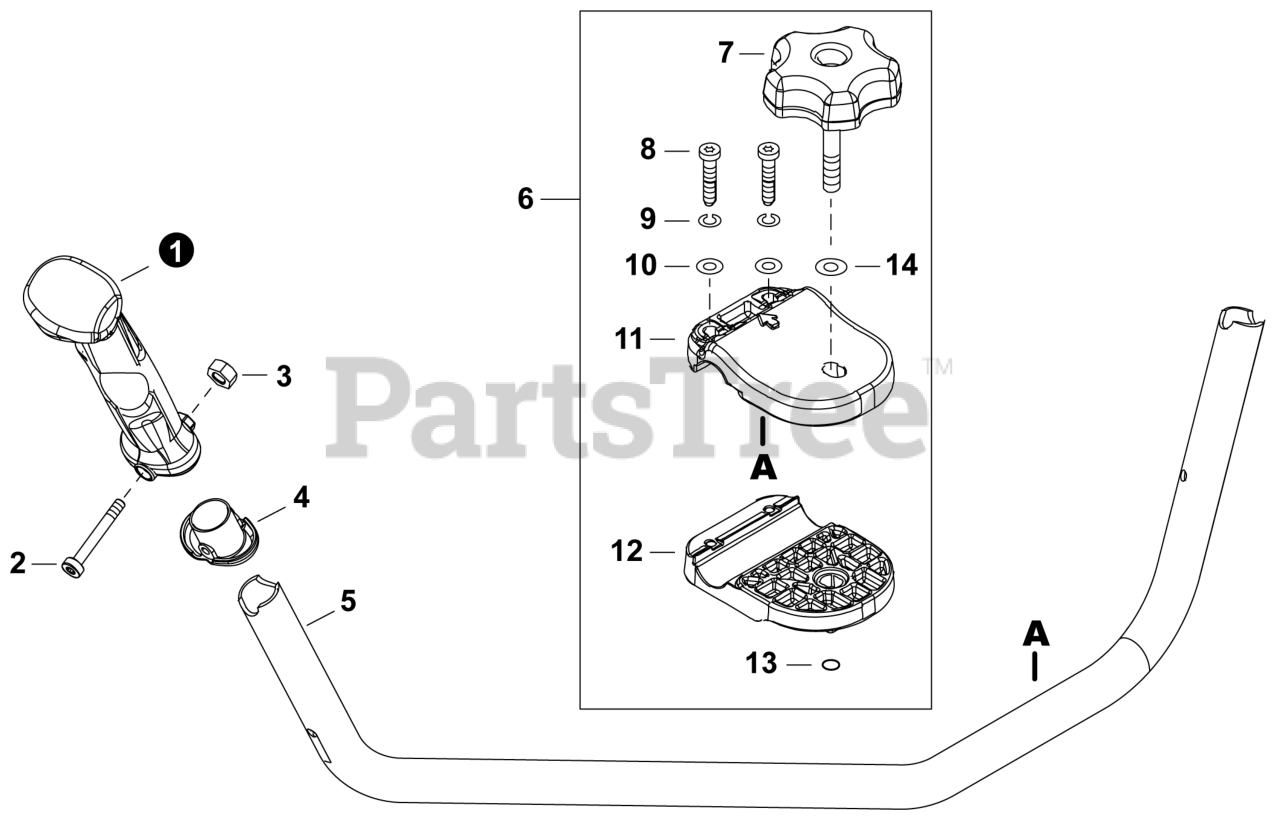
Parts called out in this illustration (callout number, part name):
1	GRIP, HANDLE
2	BOLT, TORX 5x40
3	NUT, LOCK M5
4	GUARD, HAND
5	U-HANDLE
6	BRACKET KIT, U-HANDLE
7	KNOB, SCREW M8
8	BOLT 5x30
9	WASHER, SPRING 5
11	BRACKET, HANDLE - UPPER
12	BRACKET, HANDLE - LOWER
13	O-RING 7
14	WASHER 8.2x17x1.6
